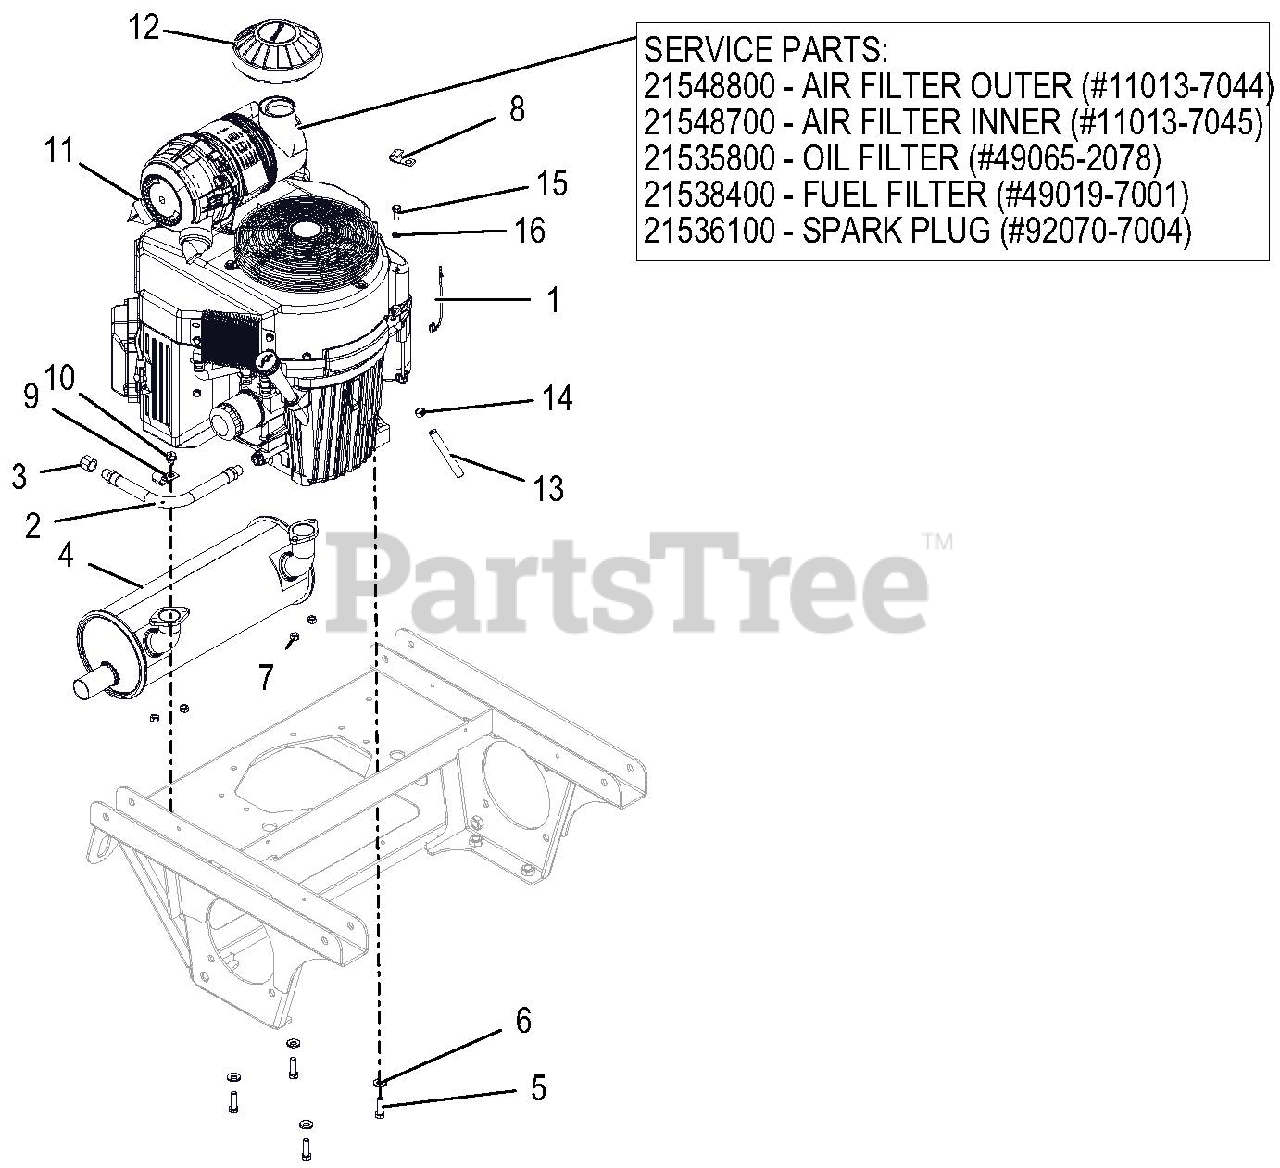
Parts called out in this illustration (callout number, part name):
1	LEAD - STARTER SOLENOID
2	HOSE, OIL DRAIN
3	PIPE CAP 3/8 NPT FEMALE
4	MUFFLER - 34HP KAWASAKI VERT.
5	BLT-HEX.38-16X1.25 G5YZ NYTORQ
6	WASHER, 3/8" SPRING DISC
7	NUT-LK-TOP M8-1.25 YWZC
10	@SCR-TAP .38-16X.50 HWH TR YWZ
11	ENGINE-KAWASAKI FX921
11	FILTER, OUTER
11	FILTER, INNER - KAW
11	FILTER,OIL - KAW
11	FUEL FILTER - KAWASAKI
11	PLUG, SPARK
12	CAP, AIR CLEANER INTAKE (2")
13	HOSE, .25 LOW-PERM BULK GAS
14	CLAMP, FUEL LINE
15	@BLT-HEX M8-1.25X20 YWZC
16	@WSHR-LK .31X.078 REG YWZC
